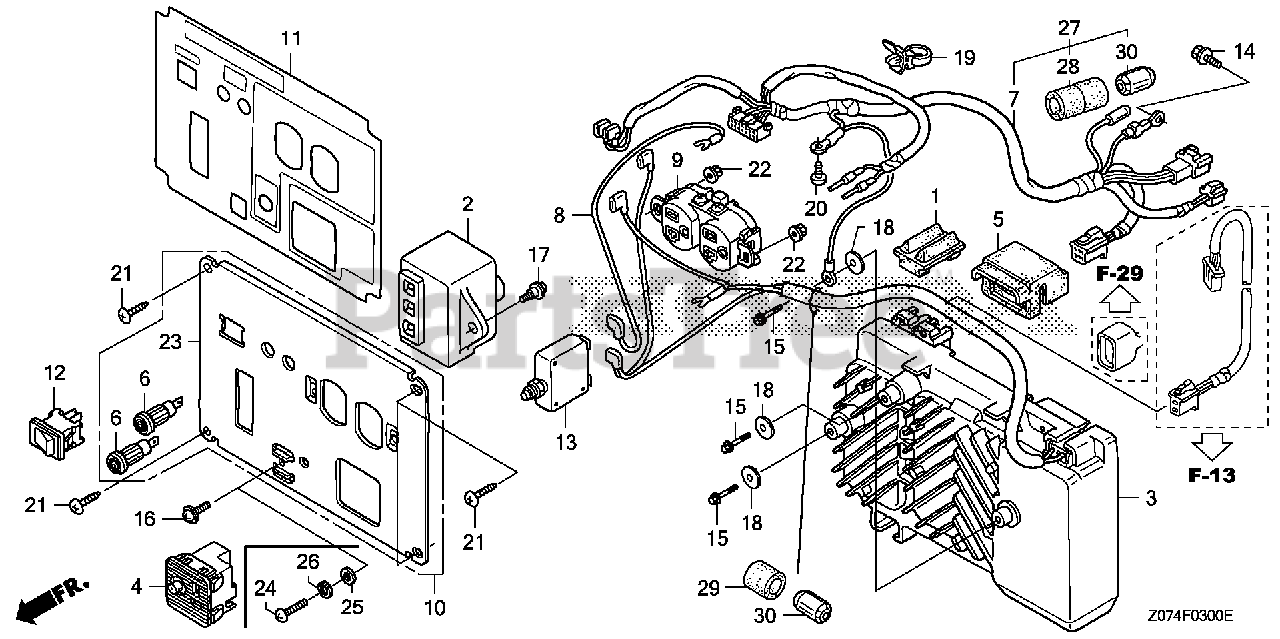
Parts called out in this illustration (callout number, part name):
1	RUBBER B, TANK MOUNTING
2	SPARK UNIT
3	INVERTER UNIT
4	RECEPTACLE, D.C.
5	COVER, CONNECTOR
6	SOCKET, COMPOSITE
7	WIRE HARNESS ASSY., CONTROL
8	WIRE, TERMINAL
9	RECEPTACLE ASSY. (125V-20A) (MATSUSHITA)
10	PANEL, CONTROL
11	MARK, CONTROL PANEL
12	SWITCH, AUTO-THROTTLE
13	PROTECTOR, CIRCUIT (20A) (WHITE)(TYCO)
14	BOLT, FLANGE (5X10)
15	BOLT, FLANGE (5X12)
16	SCREW, PAN (5X12) (GROUND CABLE)
17	SCREW, PAN (5X13)
18	WASHER, PLAIN (20MM)
19	BAND (100MM) (BLACK)
20	SCREW, PAN (5X8)
21	SCREW, TAPPING (5X16) (PO)
22	NUT, FLANGE (4MM)
23	PANEL, CONTROL
